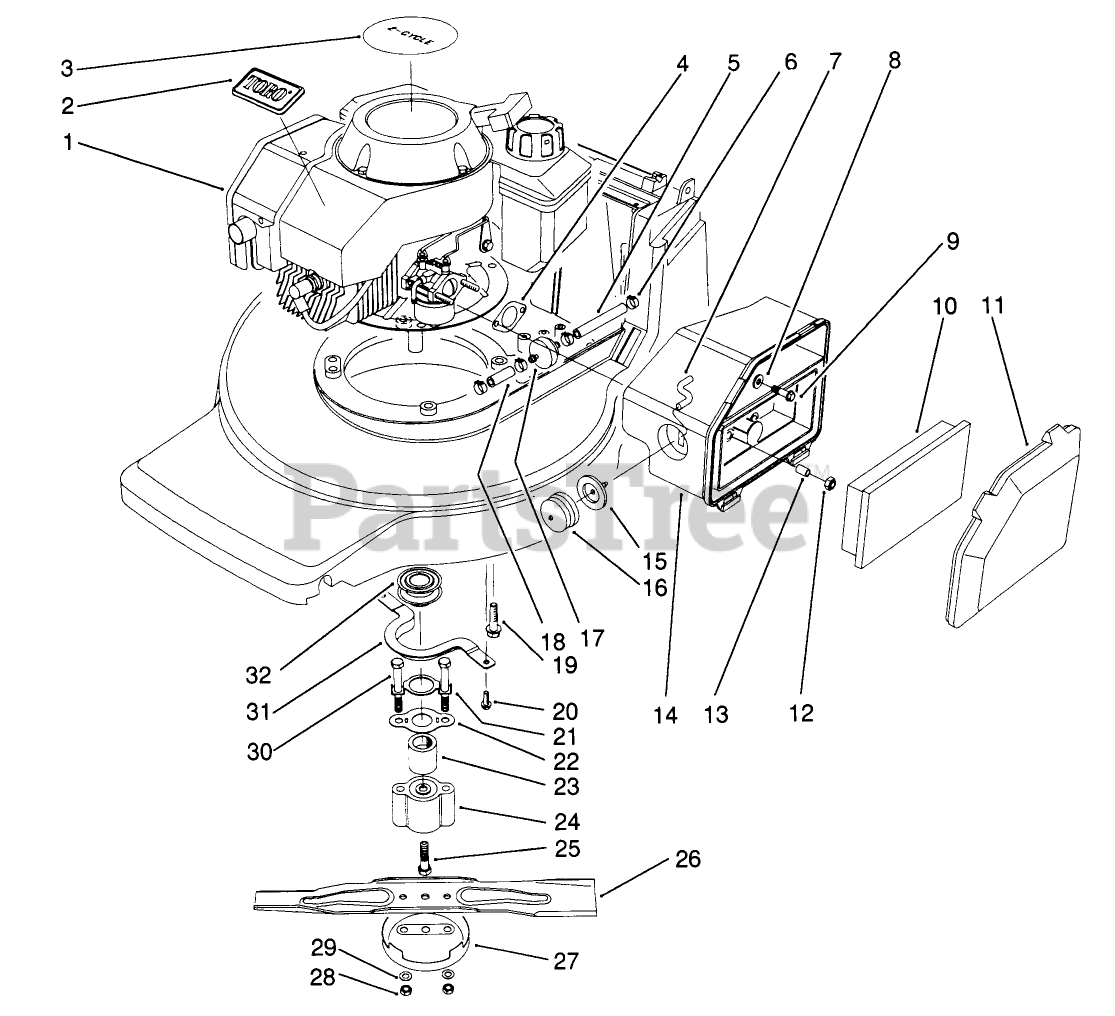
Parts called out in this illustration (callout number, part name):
1	ENGINE 121CC INT'L 2CYC
2	TORO LOGO PLT
3	DECAL- 2 CYC RECOIL
4	GASKET-AIR CLEANER
5	HOSE-FUEL
6	CLAMP-FUEL LINE
7	HOSE-PRIMER
8	WASHER-FLAT
9	SCREW-HH
10	ELEMENT-AIR CLEANER
11	COVER-AIR CLEANER
13	SPACER
14	BODY-AIR CLEANER
15	BODY-PRIMER
16	BULB-PRIMER
17	FILTER-FUEL
18	HOSE-FUEL
19	SCREW-HHF, WHIZ
20	SCREW-HWH
21	BLADE RETAINER BRKT
22	SPRING FRICTION
24	RETAINER
25	SCREW - CRANKSHAFT
26	Blade-48cm
27	Anti Scalp Cup
28	Nut
29	WASHER
30	SCREW - BLADE
31	Guide-Belt
32	PULLEY-DRIVE, ZONE START
